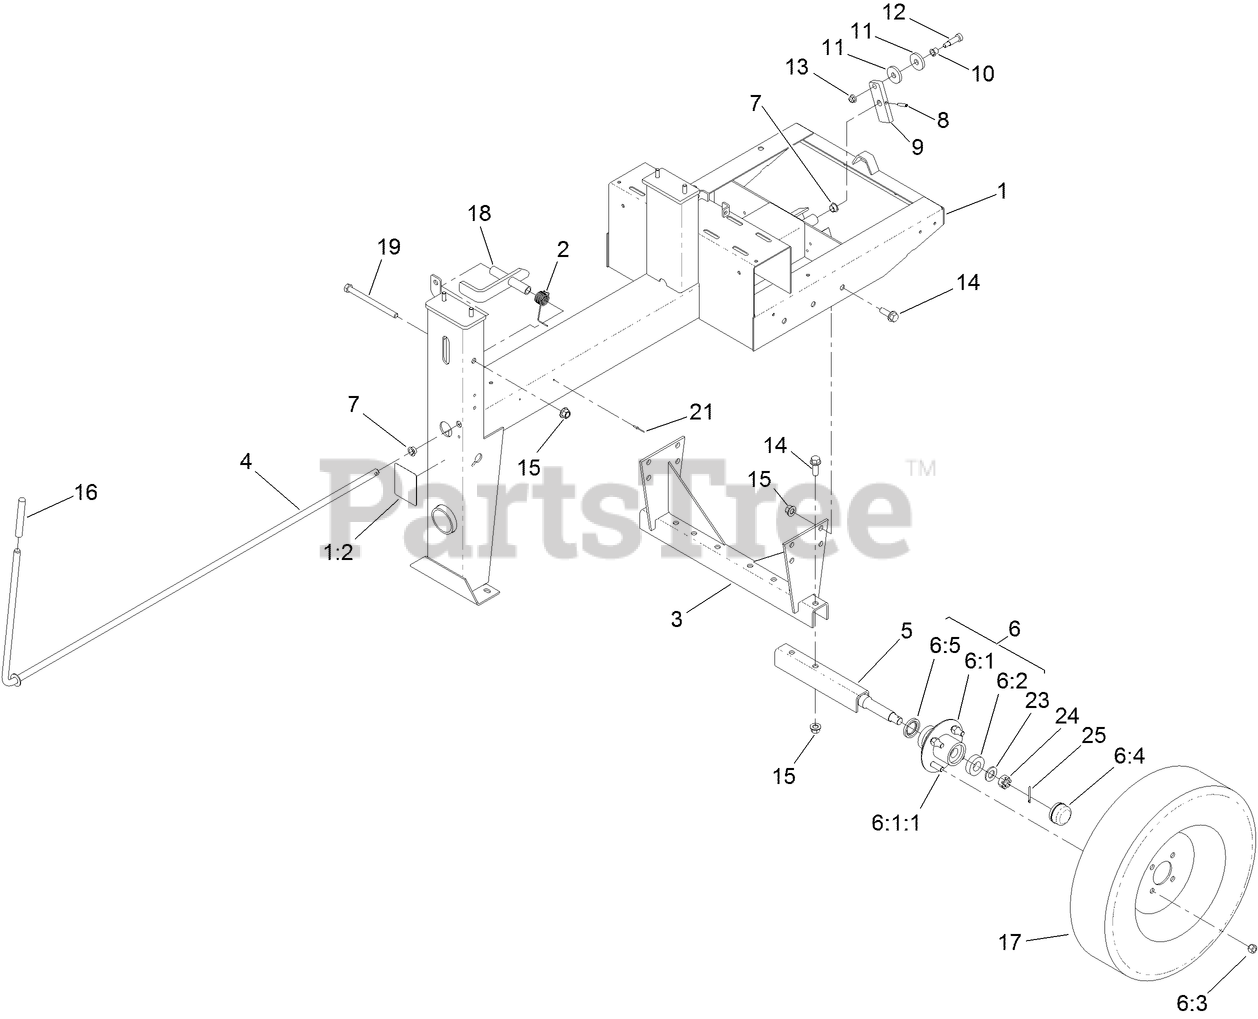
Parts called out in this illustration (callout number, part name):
1	FRAME ASM
1:2	DECAL-SAFETY CHAIN, TOWING
2	SPRING-TORSION
3	SUPPORT-AXLE
4	LEVER-CLUTCH
5	AXLE-HALF
6	HUB ASM
6:1	HUB-4IN
6:1:1	STUD-WHEEL
6:2	BEARING-ROLLER
6:3	NUT-LUG
6:4	CAP-DUST
6:5	SEAL-HUB, WHEEL
7	BUSHING-FLANGE
8	PIN-SPRING
9	LINK-CLUTCH
10	BUSHING-FLANGE
11	WASHER-FLAT
12	SCREW-HSBH
13	NUT-HF, NI
14	SCREW-HHF
15	NUT-LOCK
16	GRIP-HANDLE
17	TIRE AND RIM ASM
18	LATCH-DRUM
19	SCREW-HH
21	RIVET
23	WASHER-FLAT
25	PIN-COTTER
